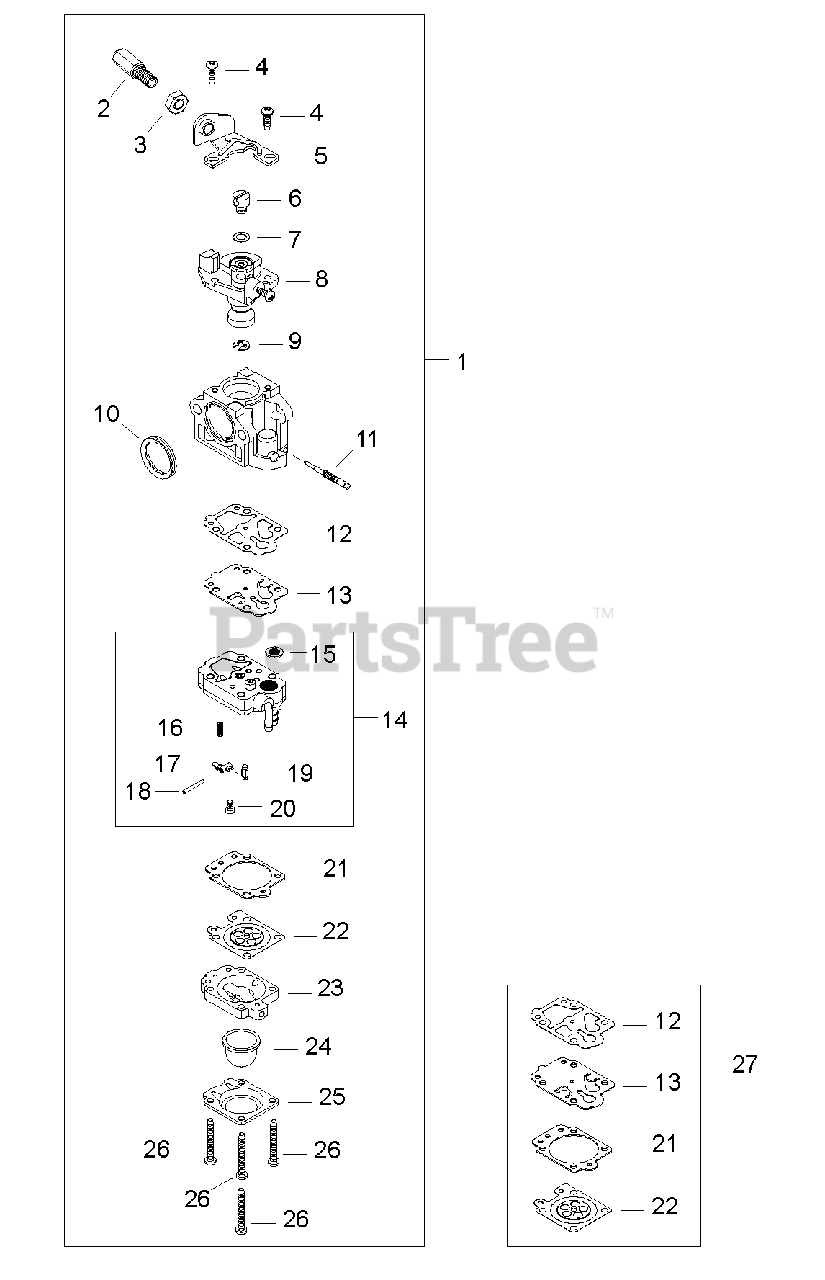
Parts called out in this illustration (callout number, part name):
1	CARBURETOR WYK
2	THROTTLE CABLE ADJUSTER
3	NUT
4	SCREW
5	BRACKET, CABLE
6	SWIVEL
7	WASHER
8	THROTTLE VALVE ASSY
9	RING, RETAINING
10	SEAL
11	NEEDLE - HIGH SPEED
12	GASKET, PUMP
13	DIAPHRAGM, PUMP
14	PUMP BODY ASSY
15	STRAINER
16	SPRING, METERING LEVER
17	LEVER, METERING
18	PIN, METERING LEVER
19	VALVE, INLET NEEDLE
20	SCREW, METERING LEVER PIN
21	GASKET, METERING
22	DIAPHRAGM, METERING
23	BASE, PURGE
24	BULB, PURGE
25	RETAINER, PURGE BULB
26	SCREW, PUMP COVER
27	DIAPHRAGM/GASKET KIT
